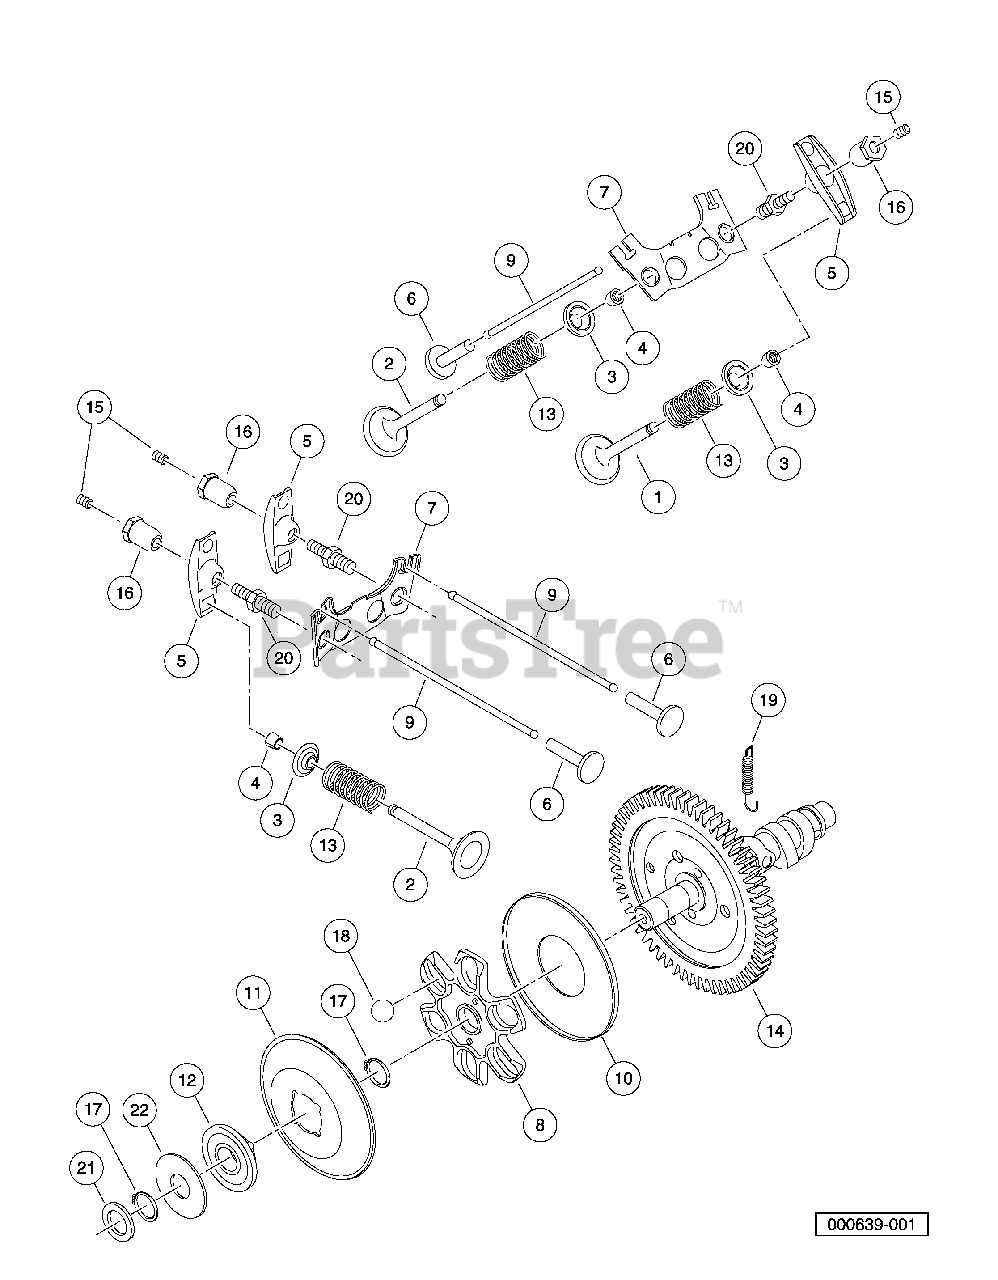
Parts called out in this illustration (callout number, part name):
1	Valve, Intake, Fh
2	Valve, Exhaust, Fh
3	Retainer, Valve Spring, Fh
4	Collet, Spring, Valve, Fh
5	Arm, Rocker
6	Tappet, Rod, Push, Fh
7	Guide, Arm, Rocker, Fh
8	Guide, Camshaft, Gov, Fh
9	Rod, Push, Fh
10	Plate, Camshaft, Gov, Fh
11	Plate, Ring, Gov, Fh
12	Sleeve, Plate, Gov, Fh
13	Spring, Valve, Fh
14	Kit, Camshaft, Comp, Fh
15	Screw, Rocker Arm, Fh
16	Nut, Arm, Rocker, Fh
17	Ring, Snap, Gov, Fh
18	Ball, Guide, Gov, Fh
19	Spring, Camshaft, Fh
20	Stud, Rocker Arm, Fh
21	Washer, Sleeve, Gov, Fh
22	Washer, Gov, Fh
